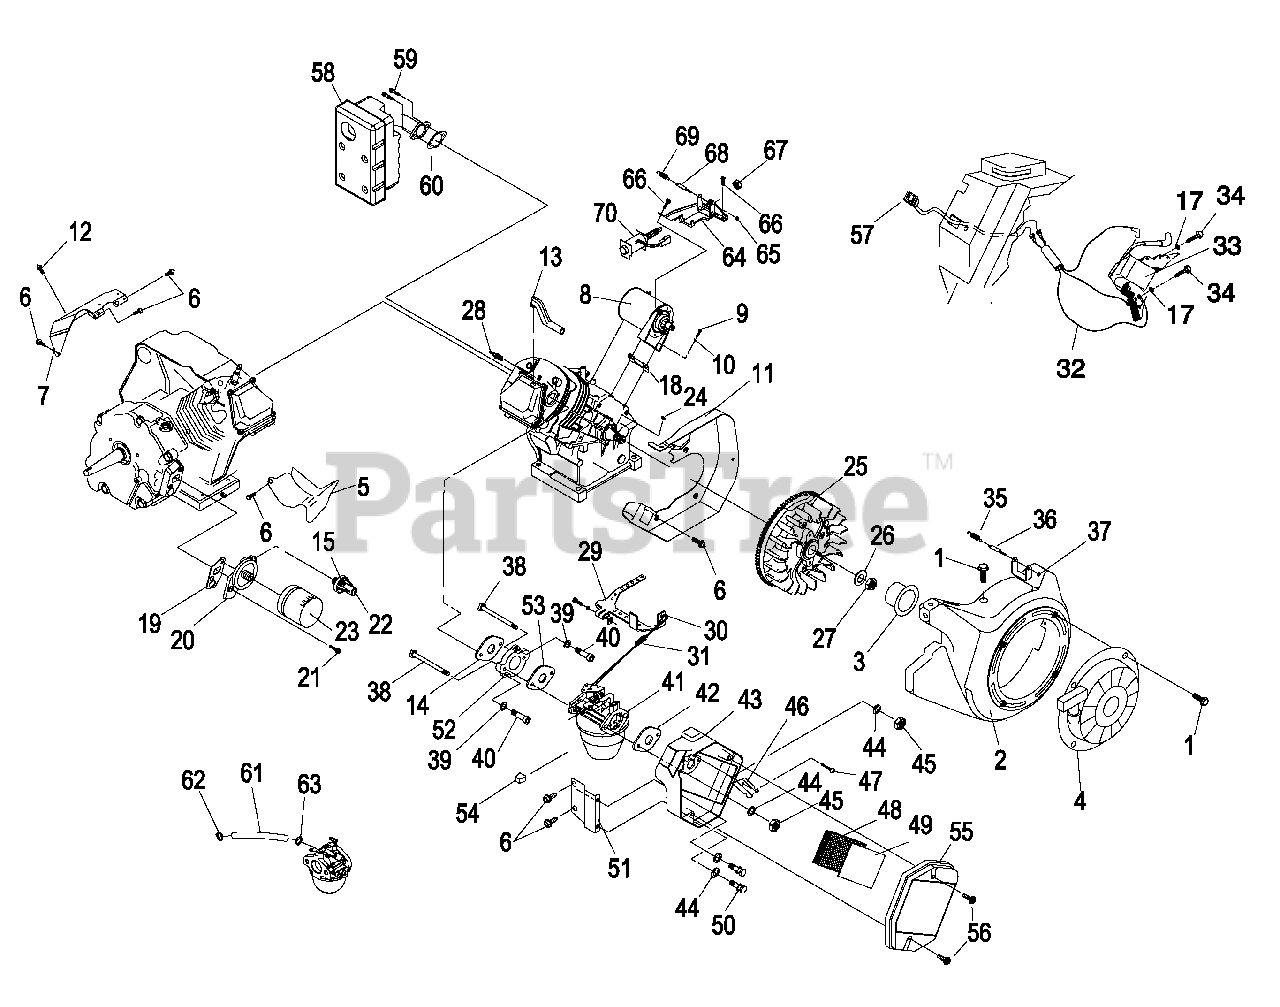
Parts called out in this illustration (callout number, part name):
1	SCREW HHTT M6-1.0 X 8 ZYC
2	ASSEMBLY, BLOWER HOUSING
3	PULLEY STARTER LARGE FRAME
4	RECOIL STARTER LARGE FRAME
5	WRAPPER, BOTTOM 12 HP HS
6	SCREW HHTT M6-1.0 X 10 YELLOW CHROME
7	WRAPPER, TOP REGULAR STEEL
8	ASSEMBLY, STARTER 46
9	SCREW, SHC M8-1.25 X 45 G12.9
10	WASHER, LOCK M8-5/16
11	BACKPLATE, W/ ELECTRIC START
12	SCREW, HHTT M8-1.25 X 16 YELLOW CHROME
13	HOSE, BREATHER GH410 ENGINES
14	GASKET, INTAKE ADAPTER
15	SCREW PPHM #8-32 X 1/4
17	WASHER, LOCK M6-1/4
18	SPACER, ENDFRAME GH 410
19	GASKET,OIL FILTER ADAPTER
20	ADAPTER, OIL FILTER NO TAPPED HOLES
21	SCREW, SHC M8-1.25 X 30 G12.9
22	SWITCH, HOBBS OIL PRESSURE 5PSI
23	FILTER, OIL BLACK 75 LONG
24	KEY, WOODRFF 4 X 19D
25	FLYWHEEL, WITH RING GEAR 27 DEGREE
26	WASHER,BELV-20 X 2.2
27	NUT HEX M20-1.5 G8 YLW CHROME-FLYWHEEL
28	SPARKPLUG, CHAMPION RC14YC
29	ASSEMBLY,GOVERNOR LEVER 12HP
30	ROD, GOVERNOR CONTROL
31	SPRING, ANTI-LASH
32	ENGINE HARNESS, PORTABLE
33	ASSEMBLY, IGNITION ADV NO DIODE GH410
34	SCREW, HHTT M6-1.0 X 25 ZINC
35	SPRING GOVERNOR 320/360/410
36	BOLT, GOVERNOR ADJUSTMENT M5
37	NUT, HEX LOCK M5-0.8 NYLON INSERT ZINC
38	BOLT, CARBURETOR MOUNTING
40	SCREW, SHC M6-1.0 X 20 G12.9 ZINC PLATED
41	CARBURETOR, 410HS
42	GASKET, AIR CLEANER
43	BASE, AIR CLEANER 410 HI FLOW
44	WASHER, FLAT M6
45	NUT, HEX LOCK M6-1.0 NYLON INSERT
46	PLATE, SPITBACK
47	SCREW, PLASTITE #8 X .37 LONG
48	ELEMENT, AIR FILTER
49	PRECLEANER, AIR FILTER
50	SCREW, HHC M6-1.0 X 16 W/ LOCK WASHER
51	BRACKET, AIR CLEANER
52	ADAPTER, "K"
53	GASKET, CARBURETOR/MANIFOLD
54	KNOB, CHOKE LEVER
55	COVER, AIR CLEANER 13GN
56	BOLT, AIR CLEANER COVER
57	SWITCH, ENGINE RUN-STOP
58	MUFFLER, 410 SIDE-OUT ALUMINIZED
59	SCREW, SHC M8-1.25 X 20 G12.9
60	GASKET, EXHAUST
61	HOSE,1/4" SAE30R7 SETIFLEX 6"
62	CLAMP, HOSE BAND 1/2"
63	CLAMP, HOSE WORM GEAR
64	GOVERNOR BRKT.
65	NUT HEX LOCK M5-0.8 NYINS ZINC
66	SCREW, TAPTITE M8 X 15
67	NUT, JAM M8-1.25
68	SCREW, ADJUST
69	SPRING, 60 Hz GOV.
70	ASSEMBLY, IDLE COIL
